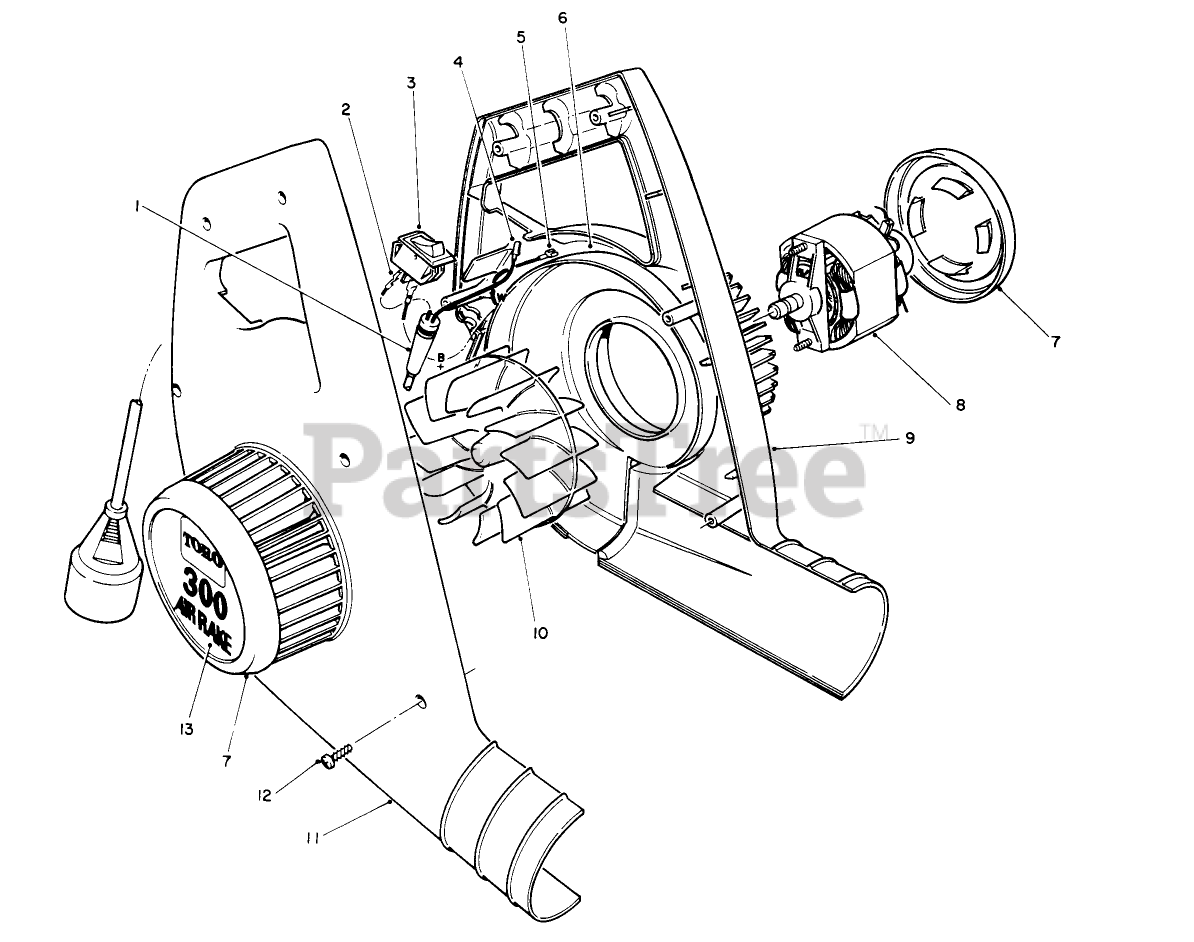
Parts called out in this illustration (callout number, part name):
1	POWER SUPPLY CORD
2	TERMINAL- 1/4", XFORMER
3	ROCKER SWITCH W/LETTERS
4	MALE COUPLER
5	FEMALE COUPLER
6	MOTOR CVR,300 BLWR(120V
7	MINI BV-INTAKE COVER
8	MOTOR, 120V MINI-BLOWER
9	Housing-L.H.
10	MINI BL-IMPELLER
11	HOUSING,RH,MINI-BLOWER
12	Screw
13	DECAL - INSTRUCTION
